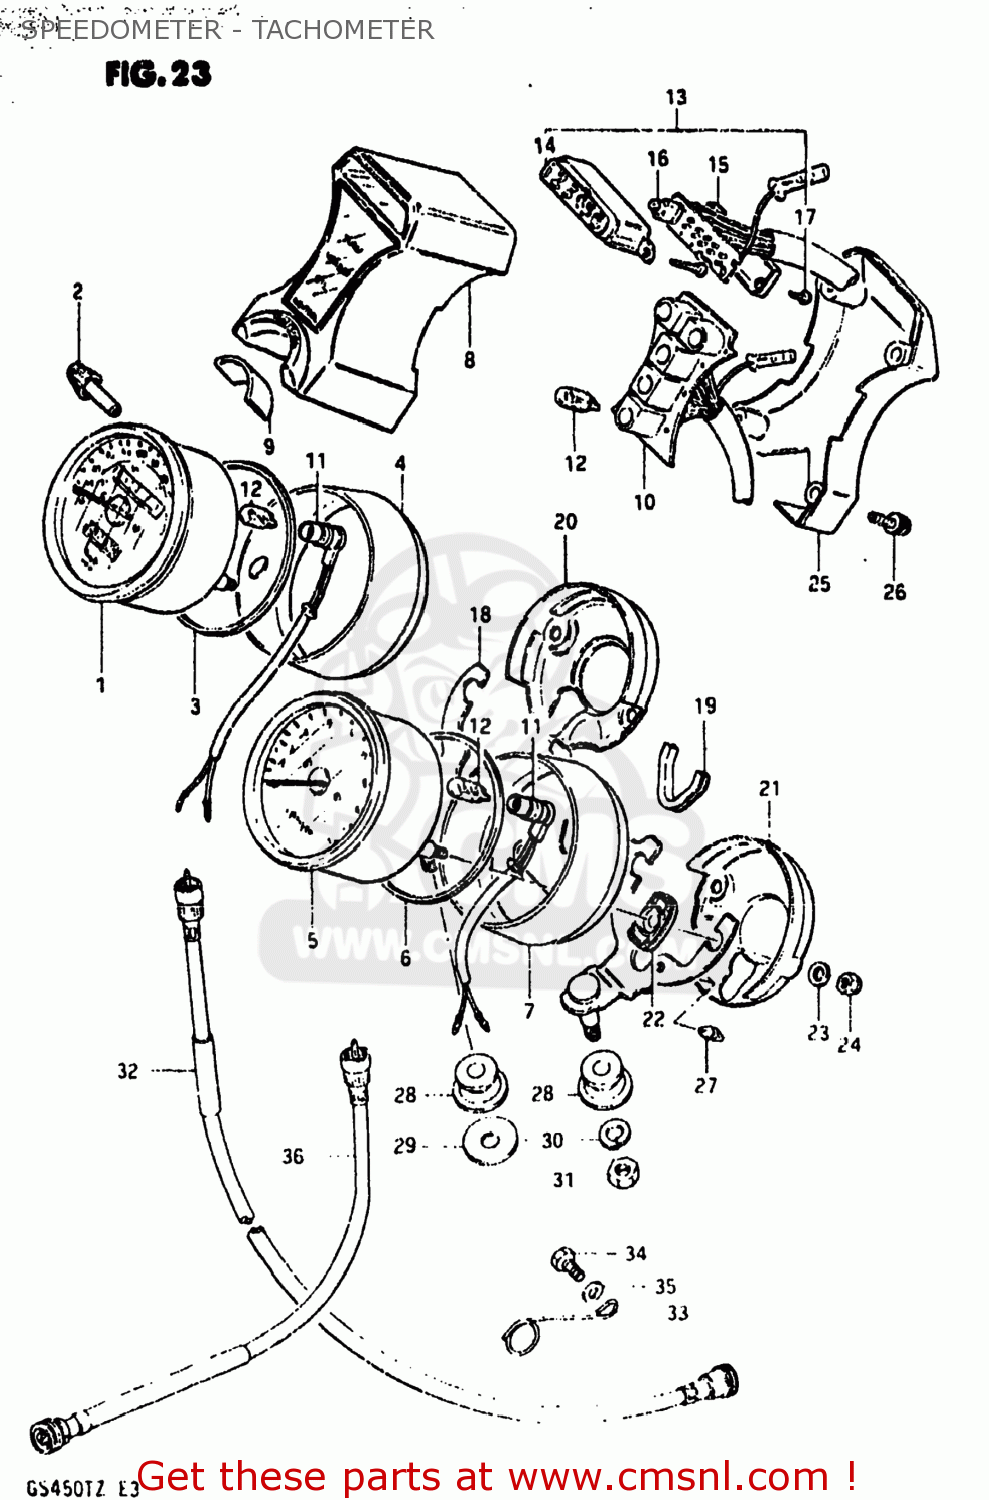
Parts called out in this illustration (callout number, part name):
1	METER,SPEEDOMETER
2	KNOB
3	CUSHION
4	COVER,SPEEDOMETER
5	TACHOMETER
6	CUSHION
7	COVER,TACHOMETER
8	CASE,PILOT BULB
9	SEAL,IGNITION SWITCH
10	SOCKET
11	SOCKET,METER
12	BULB(12V3.4W,T10)
13	INDICATOR ASSEMBLY,GEAR POSITION
14	CASE,GEAR INDICATOR
15	COVER,LWR
16	BULB(14V1.12W)
17	SCREW,GEAR INDICATOR
18	BRACKET,METER
19	BRACKET,COVER
20	ORNAMENT,SPEEDOMETER
21	COVER,TACHOMETER
22	CUSHION,METER
23	WASHER
24	NUT
25	COVER,PILOT BOX LWR
26	SCREW,PILOT BULB CASE
27	CUSHION
28	CUSHION,METER BRACKET
29	WASHER (8.5X29X1.6)
30	LOCK WASHER
31	NUT
32	CABLE ASSEMBLY,SPEEDOMETER
33	CLAMP,SPEEDOMETER CABLE
34	BOLT, UPPER
35	WASHER
36	CABLE ASSEMBLY,TACHOMETER
